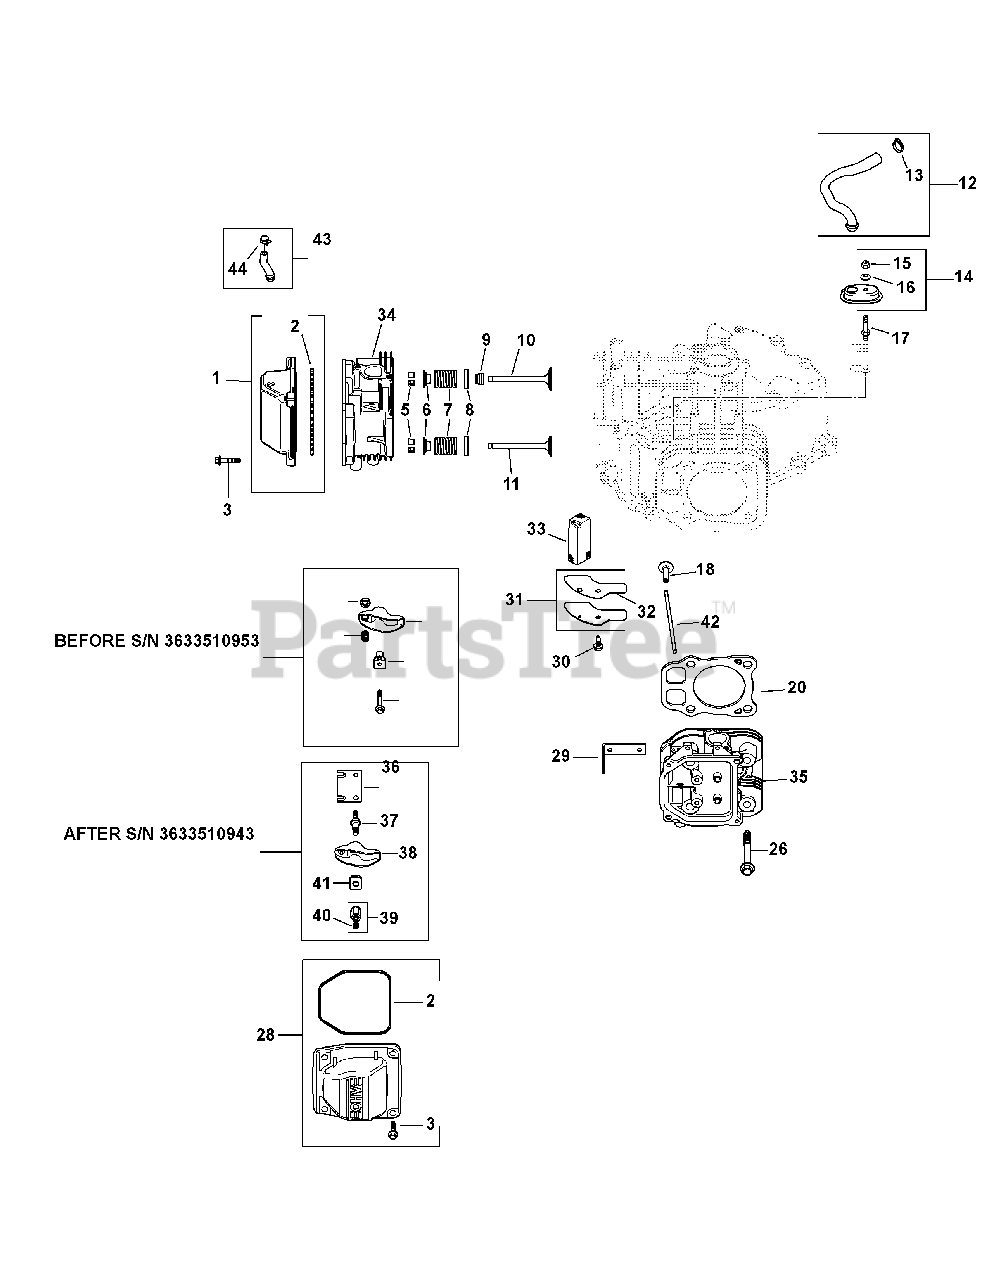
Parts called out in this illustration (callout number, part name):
1	Breather Valve Cover Kit
2	Valve Cover O-Ring
3	Flg. Screw, M6 X 1.0 X 30
5	Retainer Kit
6	Valve Spring Cap
7	Valve Spring
8	Spring Retainer
9	Valve Stem Seal
10	Intake Valve (Std)
11	Exhaust Valve (Std)
12	Kit, Breather Hose Kit
13	Hose Clamp, 1.2
14	Breather Housing Kit
15	Lock Nut, M 5 X .8
16	Sealing Washer
17	Breather Cover Stud
20	Cylinder Head Gasket Kit
26	Flg. Screw, M 10 X 1.5 X 90
28	Breather Valve Cover Kit
29	Lifting Strap
30	Flg. Thd. Frm. Screw, M6 X 1.0 X 16
31	Breather Cover Kit
32	Fuse Block
33	Breather Filter
34	#1 Cylinder Head Assembly Kit
35	#2 Cylinder Head Assembly Kit
39	Hex Nut Assembly
41	Rocker Arm Pivot
43	Fuel Pump Hose w/ Clamp Kit
